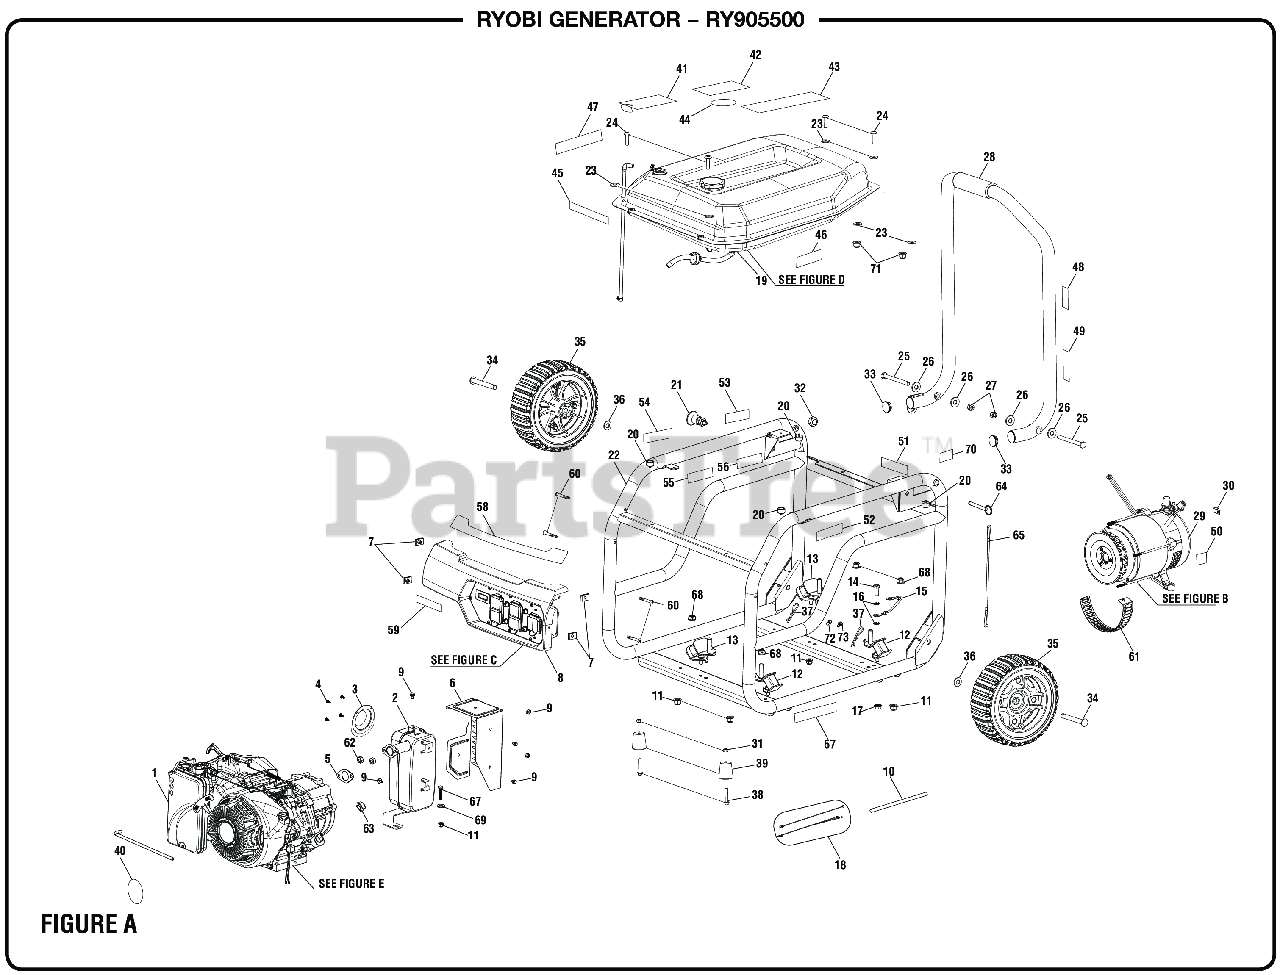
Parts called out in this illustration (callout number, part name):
3	Spark Arrester Screen
4	Screw (8-32 x 3/8 in., Pan Hd.)
5	Exhaust Gasket
6	Heat Shield
7	U-Clip (M6)
8	Control Panel Assembly
9	Bolt (M6 x 9 mm, Hex Flange Hd.)
10	Heat Shrink Tube
11	Lock Nut (M8 x 1.25 mm, Flange)
12	Engine Isolator (Large)
13	Engine Isolator (Right)
14	Bolt (5/16-18 x 3/4 in., Hex. Hd.)
15	Assembly, ground wire
16	Washer (5/16 in., External Star)
17	Flange Nut (5/16-18, Hex Hd.)
18	Wire Assembly
19	Fuel System
20	Handle Bumper
21	Quick Release Pin Assembly
22	Carrier Assembly
23	Washer (1/4 in., Type A)
24	Screw (1/4-20 x 1 in., T30 Torx Hd.)
25	Handle Pivot Pin (5/6-18 x 90 mm)
26	Washer ( 5/16 in.)
27	Lock Nut (5/16-18, Hex Hd.)
28	Handle Assembly
29	Generator Head Assembly
30	Ground Lug (5/16-24) (BM903600)
31	Lock Nut (M8 x 1.25)
32	Lock Nut (1/2-20, Hex)
33	End Cap (Handle)
34	Washer (M10)
35	Handle Isolator
36	Washer (OD19.75 x ID10.5 x 1t)
37	Hitch Pin (M3)
38	Bolt (M8 x 1.25 in., Flange Hex Hd.)
39	Foot Assembly
40	Engine Recoil Label
41	Warning Hangtag
42	Warning Label
43	CPSC (English) Label
44	Remove Cap Fuel Stabilizer Label (English)
45	Logo Label
46	UL Fire Warning Label Spark Arrestor)
47	Start Label
48	Fuel Stabilizer Label (French/Spanish)
49	No E85 Label
50	Ground Label Icon
51	Ground Warning Label
52	Risk of Fire Danger Label
53	Quick Release Pin Label
54	Inquires Label (Ryobi)
55	Hot Surface and Exhaust Label
56	Fire Distance Label (Eng/Sp)
57	Engine Lubricant Label
58	Performance Label
59	Choke Label
60	Screw (M6 x 50 mm, T30 Torx Pan Hd. )
61	Fan Cover (Generator Head)
62	Hex Nut (M8 x 1.25, Special)
63	Plug (Generator Head)
64	Release Pin (5/16 x 2 in.)
65	Lanyard (3/16 in.)
67	Screw (M8 x 40 mm, Hex Hd.)
68	Lock Nut (5/16-18)
69	Washer (ID9 x OD25.4 x 2t)
70	Lock Pin Label
71	NYLON LOCK NUT (1/4-20)
72	Screw (M5 x 10 mm, Hex Hd.)
73	Bolt (M5 x 10 mm, Flange Hex Hd.)
